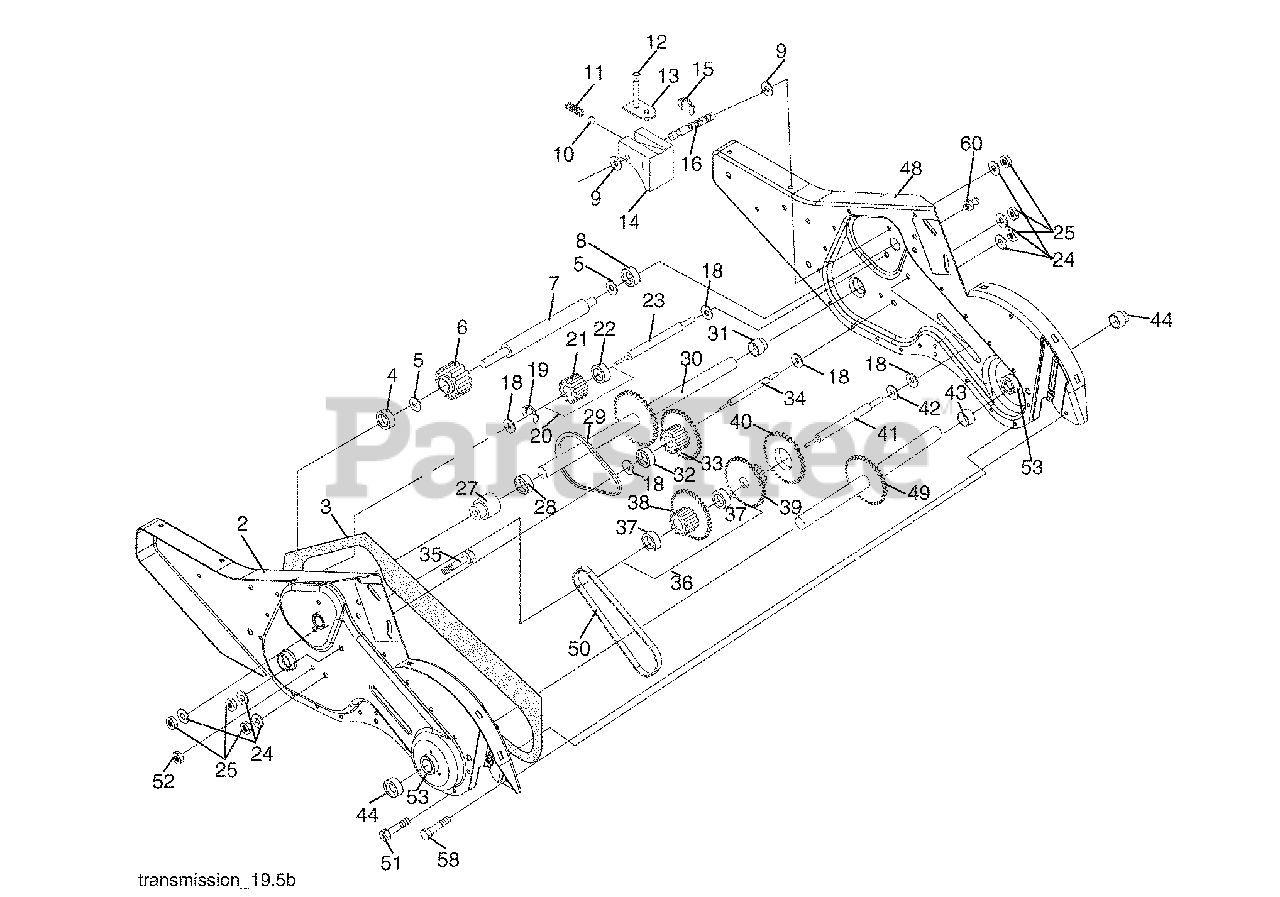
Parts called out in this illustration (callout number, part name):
1	Transmission Assembly
2	Gearcase, L.H. w/Bearing
3	Gasket, Gearcase
4	Bearing, Needle
5	Washer, Thrust 5/8 x 1.10 x 1/32
6	Pinion, Input
7	Shaft, In put
8	Bearing, Needle
9	Washer, Seal
10	Ball, Steel
11	Spring, Shift, Fork
13	Arm, Shift
14	Fork, Shift
15	Ring, Klip
16	Shaft, Shift
19	Ring, Klip
20	Gear, Assembly, Reverse Idler
21	Gear, Reverse Idler
22	Bearing, Needle
23	Shaft, Reverse Idler
24	Washer, Lock 7/16
25	Nut, Hex 7/16-20
27	Bearing, Shaft, Ground Drive L.H.
28	Spacer 0.765 x 1.125 x 1.23
29	Chain #35-50 Pitch
30	Ground Shaft Assembly
31	Bearing, Shaft, Ground Drive R.H.
32	Spacer 0.70 x 1.00 x 1.150
33	Sprocket and Gear Assembly
34	Shaft, Reduction (2nd)
35	Screw, Whiz, Lock 5/16-18 x 3-1/2
36	Sprocket Assembly w/Bearing
37	Bearing, Needle
38	Sprocket, Tine
39	Gear, Cluster, Red 1st & 2nd
40	Gear, Reverse
41	Shaft, Reduction (1st)
42	Washer, Thrust
43	Spacer 1.01 x 1.75 x 0.760
44	Seal Asm, Oil
48	Gearcase, R.H. w/Bearing
49	Shaft, Tine
50	Chain, Roller #50-50 Pitch
51	Screw 1/4-20 x 1/2
52	Nut, Hex 5/16-18
53	Kit, Bearing
58	Bolt Shoulder 1/4-20 unc x .875
60	Fitting Grease
